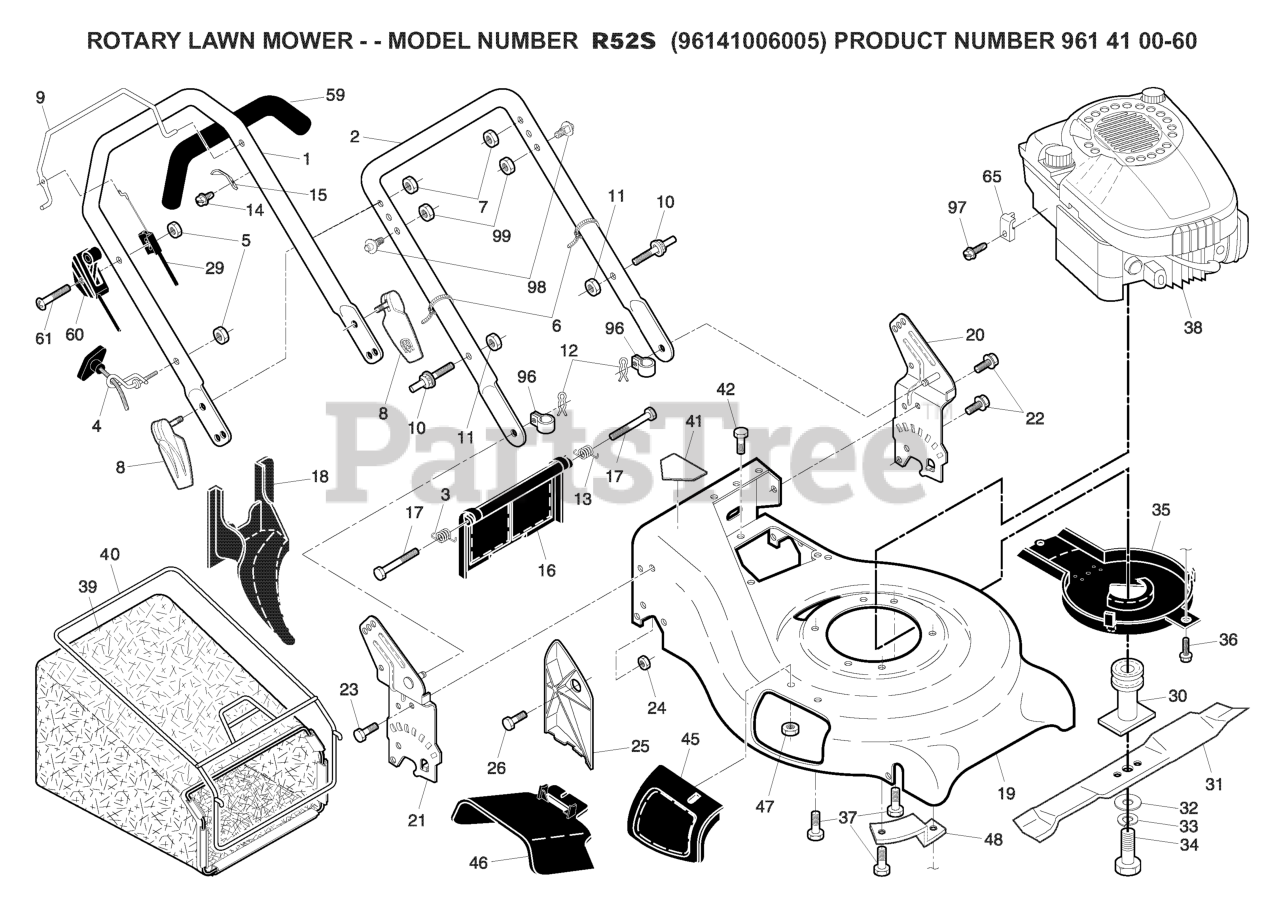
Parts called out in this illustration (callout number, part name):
2	HANDLE.LOWER.21.PNT
3	SPRING.RH.REAR.DOOR.21.RWGD
4	RB GUIDE.ROPE.STD.BLK.ZIN WSL
5	NUT
6	TIE GUIDE
7	NUT.HEX.FLANGE.1/4
8	ASM.QUICK.RELEASE
9	BAIL.CONT.COMF.PUSH.ORGANGE.RH
11	NUT.LOCK.5/16-18
12	HAIRPIN COTTER
13	SPRING.LH.REAR.DOOR.21.RWGD
15	BRACKET UPSTOP
16	REAR DOOR ASSEMBLY
18	PLUG.MULCHER.RGD.21.
19	KIT.HSG.21.RGD.MC.ORG.CE
20	BRKT.ASM.HNDL.21.RWGD.LT
21	BRKT.ASM.HNDL
22	SELF-TAPPING SCREW 5/16-18X3/4
23	BOLT, HEX HEAD 5/16-18
24	NUT.71038.31-18.HEX.NYLOCK
25	CLIPPING DEFLECTOR
29	ENGINE ZONE CONTROL
30	BLADE ADAPTOR / PULLEY
31	BLADE.21.PUSH
32	WASHER,HARDEN
33	LOCKWASHER
34	SCREW, HEX HD 3/8-24 X 1-3/8
35	DEBRIS SHIELD
36	SCREW.HEX.WSH
37	BOLT 3/8-16X1-1/8
40	FRAME.GBAG.21.RWGD.SC
41	DECAL.INTERNATIONL.CUTFINGER
45	MULCHER DOOR ASM.
46	DEFLECTOR, DISCHARGE
48	BRACKET
59	GRIP.HANDLE.FOAM
60	CONTRL.THROTTLE.
65	CABLE CLAMP(ENGINE)
96	CLIP.CABLE.BLK
97	SCREW.HEX.HEAD.WASHER.10-16
98	STUD.QUICK.ADJUST
99	NUT.LOCK.5/16-18
